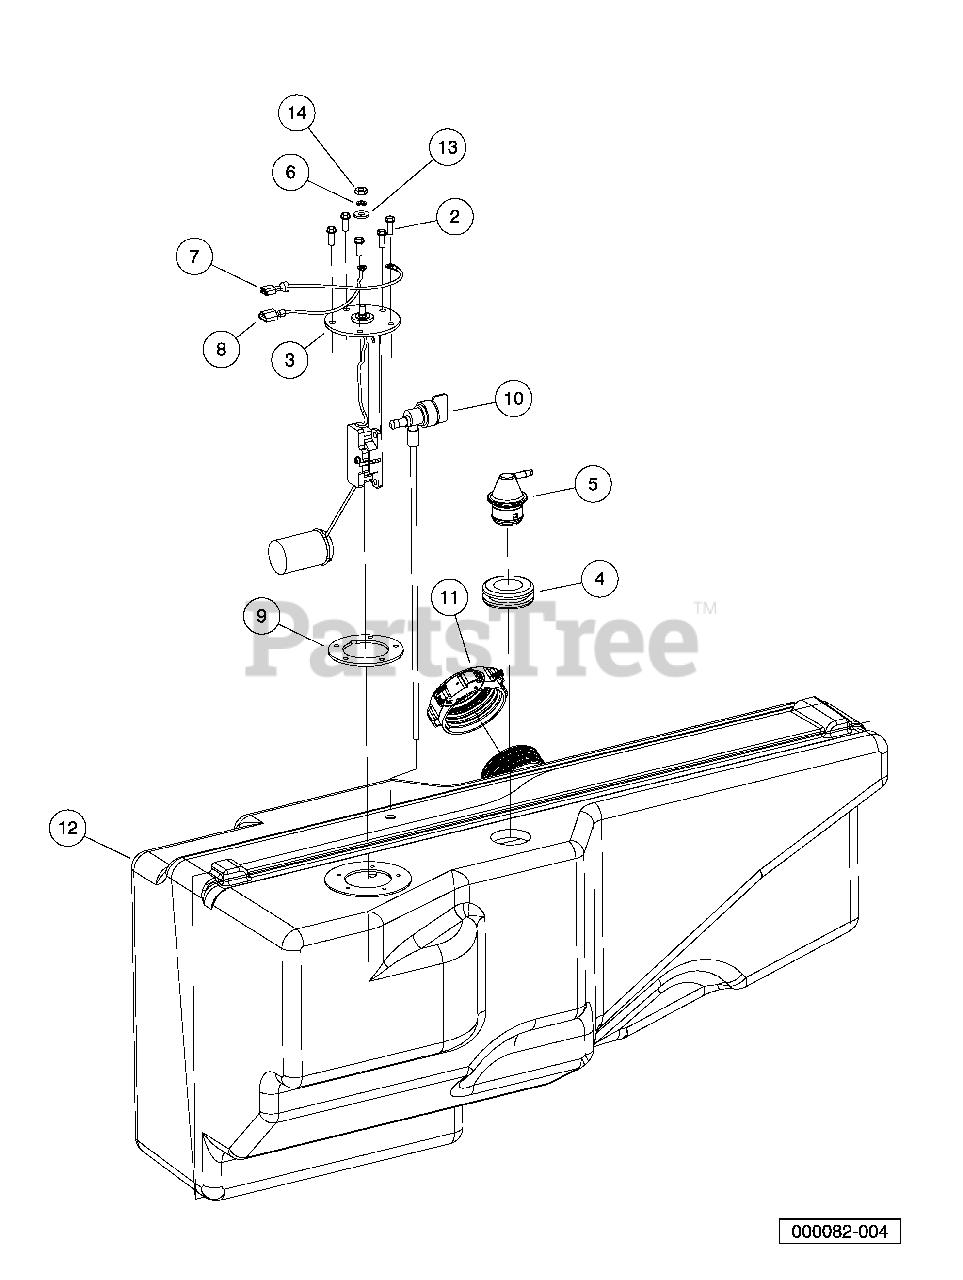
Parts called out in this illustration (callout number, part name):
1	Asm, Tank, Fuel, Gas, 4x4
2	Screw, #10-16 Hex-Head Hi-Lo
3	Sending Unit, Fuel Level *
4	Insulation Grommet
5	Vent, Fuel Tank
6	Washer, #10 Split Lock
9	Gasket, Rubber
10	Valve, Pickup Tube, Fuel
11	Cap, Fuel Tank, Gasoline
13	Washer, #10 Type A Flat
14	Nut, #10-32 Brass Hex
